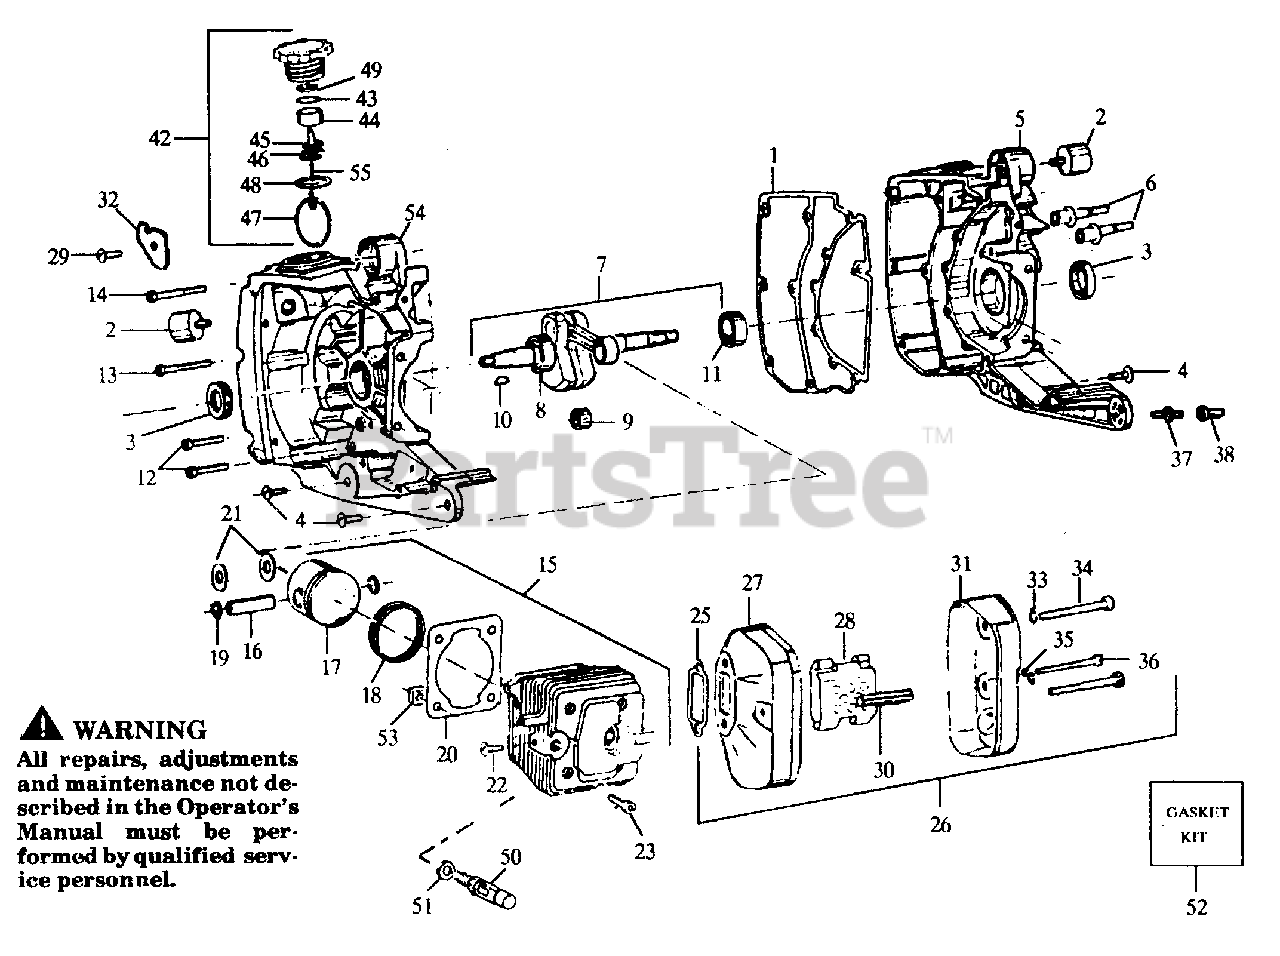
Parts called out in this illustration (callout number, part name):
1	Crankcase Gasket
2	Shock Absorber
5	C'Case & Stud Ass'y.
6	Bar Mounting Studs
7	Crankshaft Ass'y.
8	Main Bearing
10	Flywheel Key
15	Cylinder & Piston Kit
16	Wrist Pin
18	Piston/Ring Set
19	Wrist Pin Retainer
20	Cylinder Base Gasket
21	Thrust Washer
22	Plate Screw
25	Muffler Gasket
26	Muffler Ass'y.
27	Muffler Body
28	Muffler Channel
31	Muffler Cover
33	Lockwasher
34	Muffler Screw
35	Lockwasher
37	Clutch Cover Stud
38	Clutch Cover Bushing
42	Gas Cap Ass'y.
45	Umbrella Valve
46	Gas Cap Cover
47	Gas Cap Retainer
48	Gas Cap O-Ring
50	Decompression Valve
52	Gasket Set
54	Crankcase Half M/S
55	Bead Chain Gas Cap
